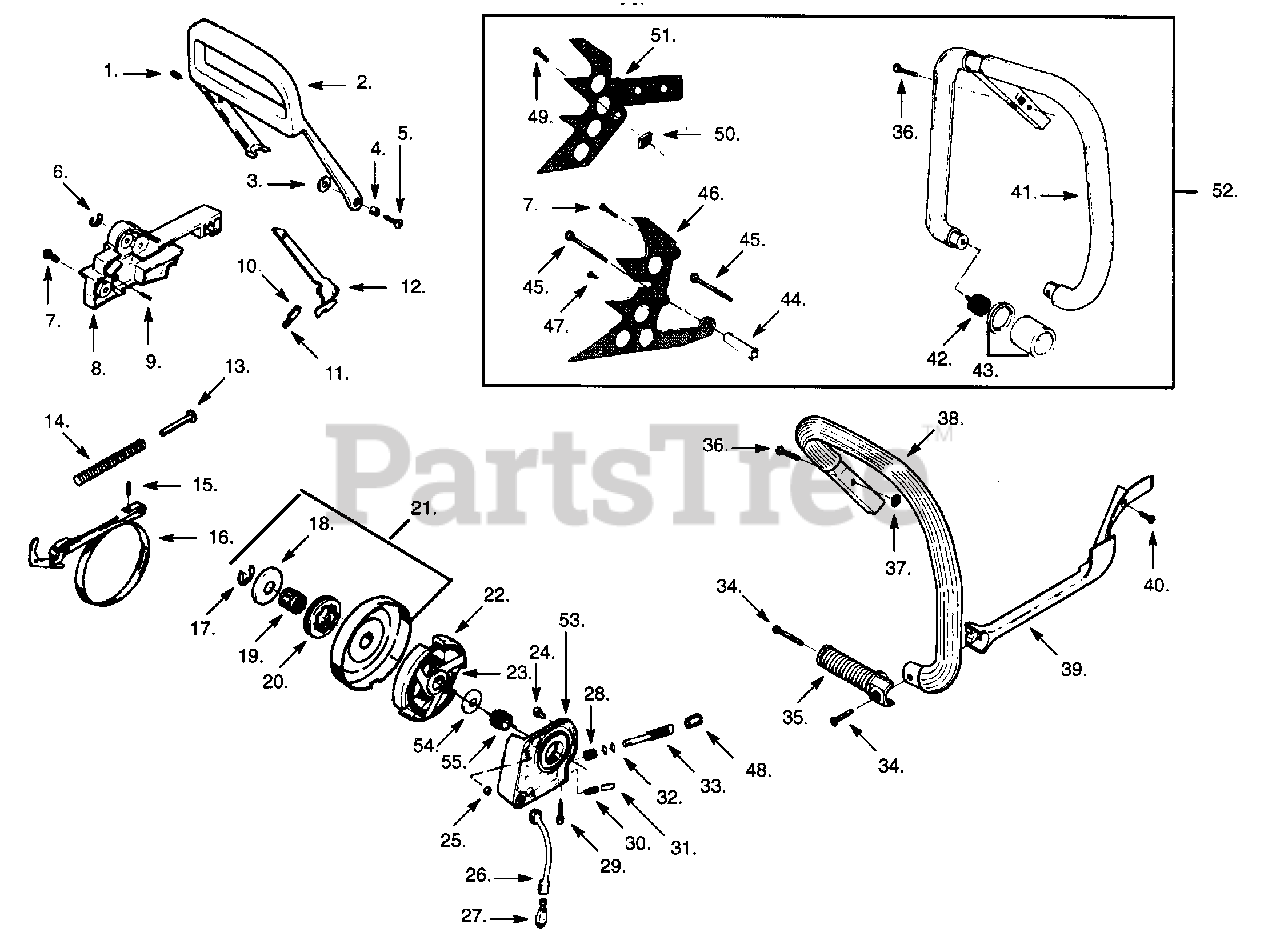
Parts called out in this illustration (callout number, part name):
2	Actuator
8	Brake Housing
12	Actuator Arm
18	Cup Washer
19	Clutch Bearing
20	Rim-3/8x7
20	Rim-3/8x8
21	Clutch Drum Ass'y.
22	Clutch Ass'y.
23	Clutch Spring
25	Seal Ring
26	Oil Pickup Tube
27	Oil Pickup
29	Adjusting Screw
33	Pump Piston
37	Nut
38	Handlebar
40	Screw
41	Handlebar
46	Inner Spur
47	Screw
48	Dust Shield
49	Screw
50	Nut
51	Outer Spur
52	Wrap Around Handlebar Kit
54	Shim Washer
55	Pump Drive Worm Gear
